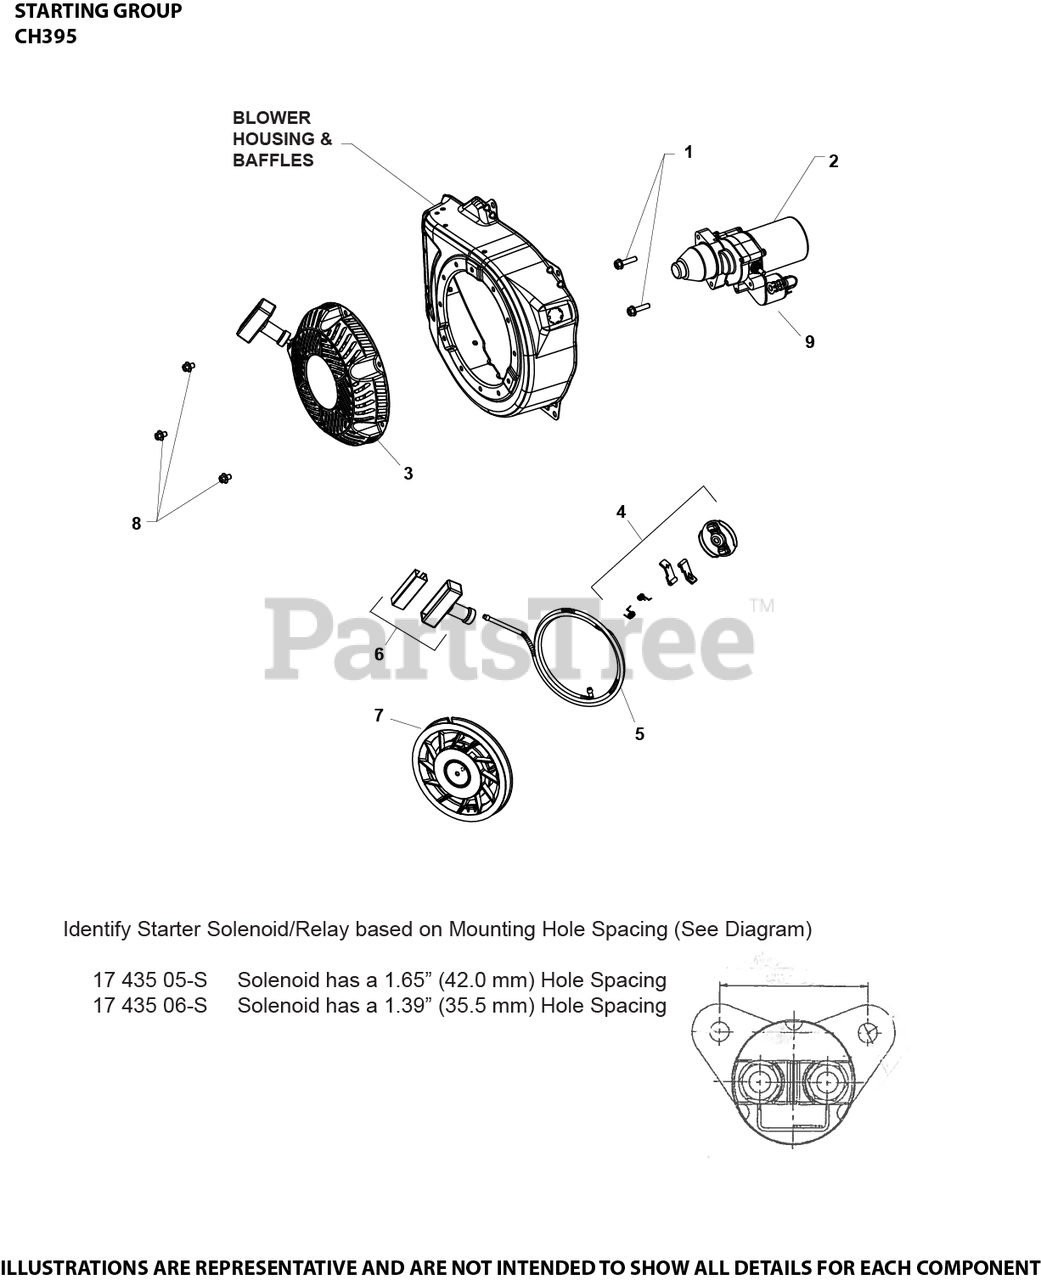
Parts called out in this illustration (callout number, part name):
3	RETRACTABLE STARTER ASSEMBLY
4	KIT, PAWL REPAIR
5	KIT, ROPE
6	KIT, HANDLE
7	PULLEY, RECOIL
8	SCREW, M6 X 8 HEX FLANGE HEAD
